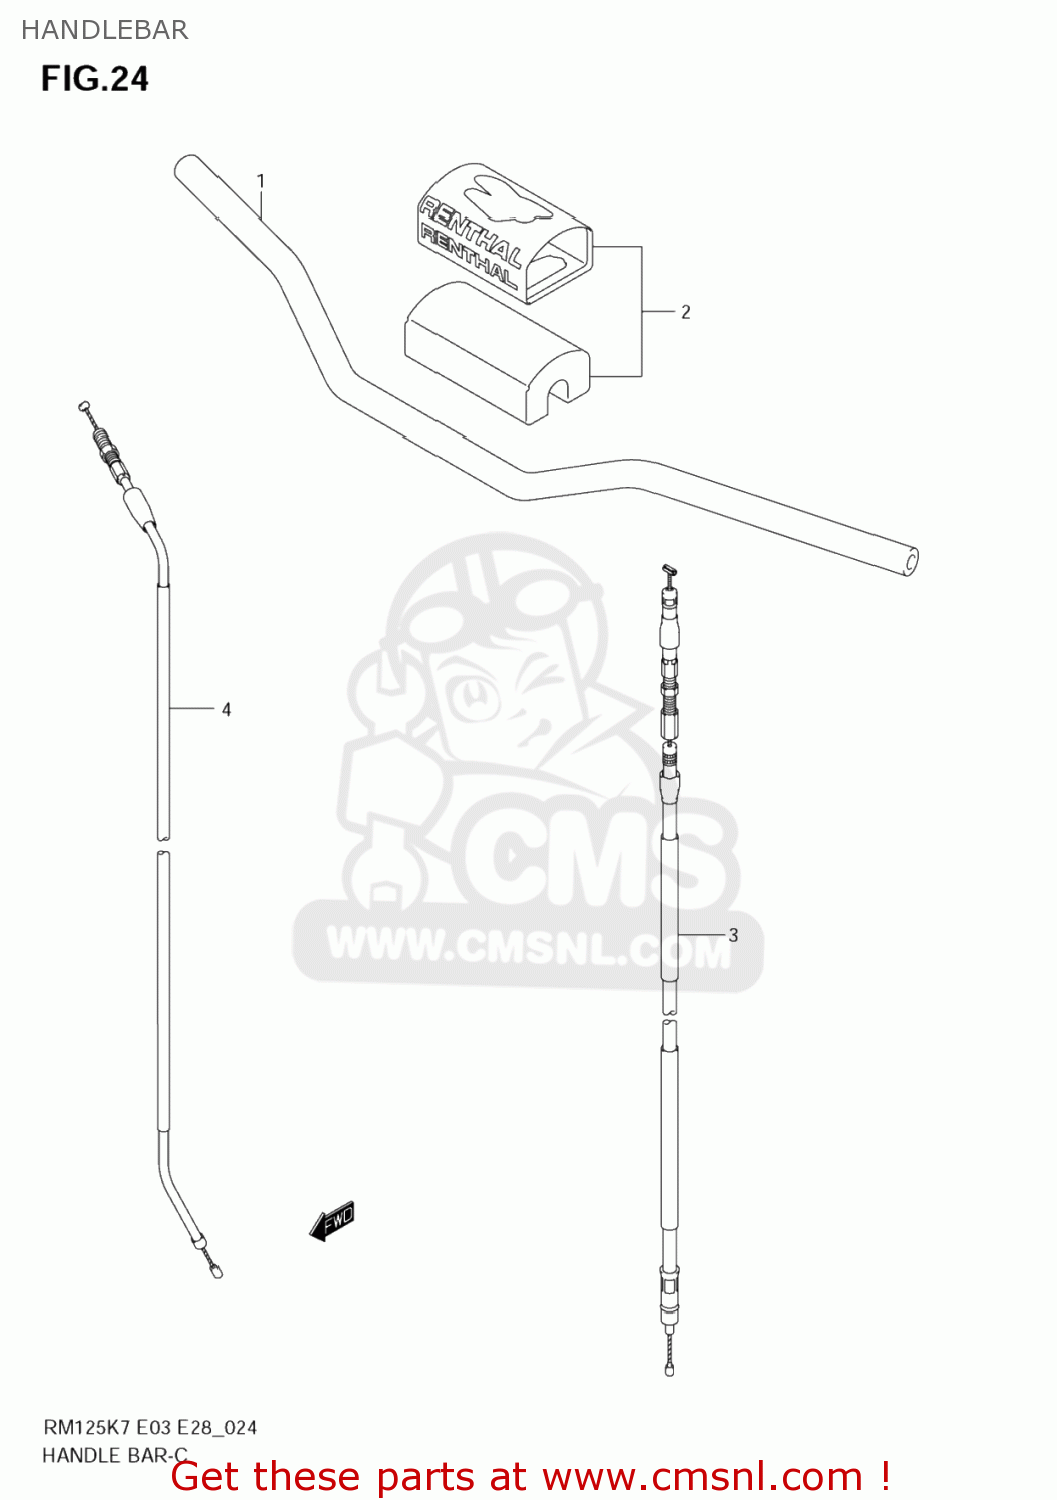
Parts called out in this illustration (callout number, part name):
1	HANDLEBAR
2	PAD SET,HANDLEBAR (NAS)
3	CABLE ASSY,CLUTCH
4	CABLE ASSY,THROTTLE
